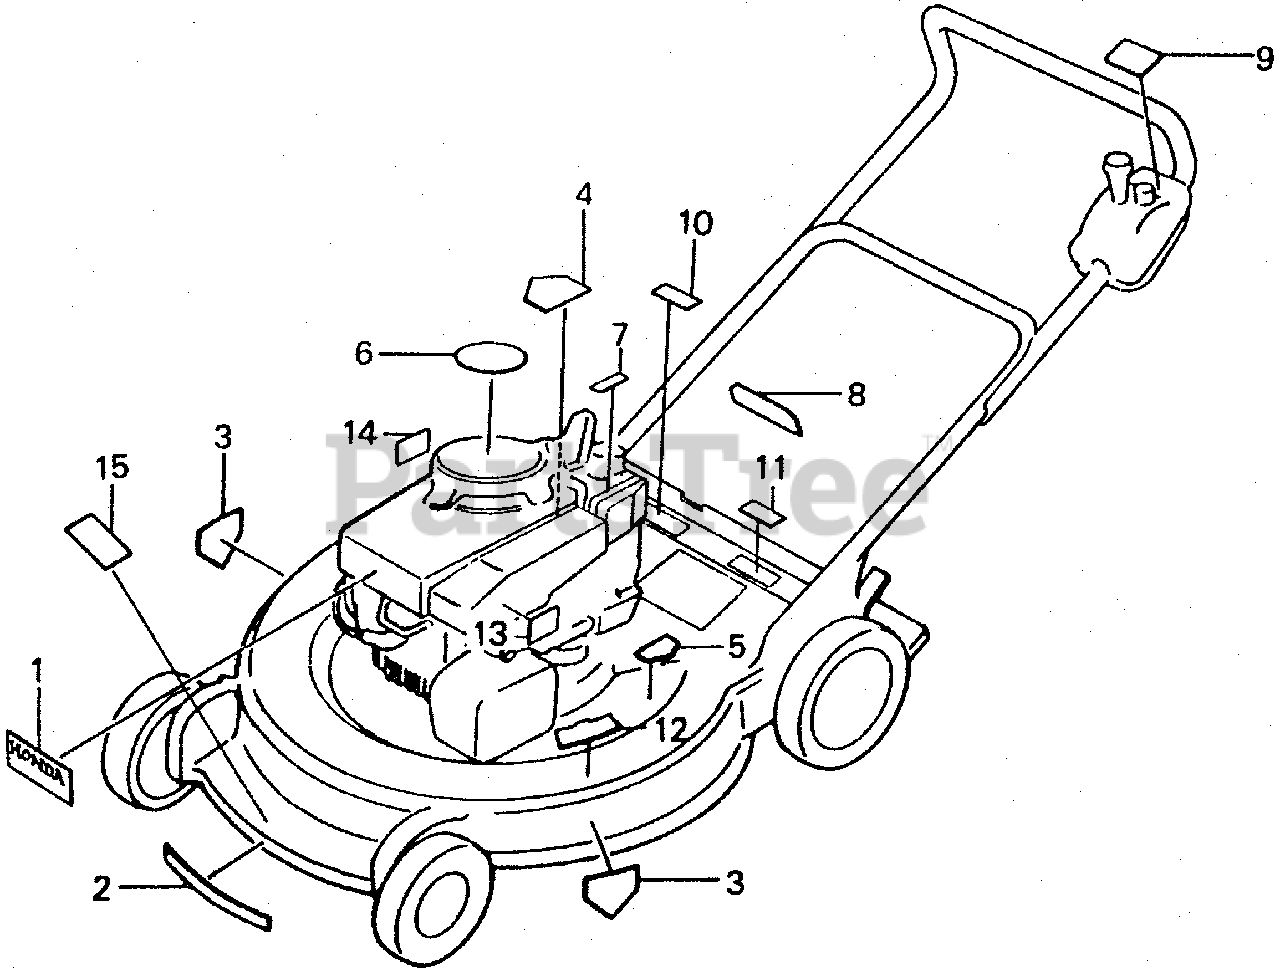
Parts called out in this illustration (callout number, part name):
1	MARK, TOP COVER (NOT AVAILABLE)
2	LABEL A, HOUSING CAUTION (ENGLISH)
3	LABEL C, HOUSING CAUTION
4	LABEL B, HOUSING CAUTION
5	LABEL, STEP POSITION (ENGLISH) (NOT AVAILABLE)
6	CAUTION, OPERATOR (ENGLISH) (NOT AVAILABLE)
7	LABEL, FUEL CAUTION (ENGLISH)
8	LABEL, DISCHARGE GUARD CAUTION (NOT AVAILABLE)
9	LABEL, CONTROL COVER CAUTION (ENGLISH) (NOT AVAILABLE)
10	MARK, DISCHARGE GUARD
11	CAUTION, BELT COVER (ENGLISH) (NOT AVAILABLE)
12	LABEL, PLUG CAUTION (ENGLISH)
13	MARK, AIR CLEANER CAUTION
14	MARK, OIL CAUTION
15	MARK, TYPE (SD) (NOT AVAILABLE)
